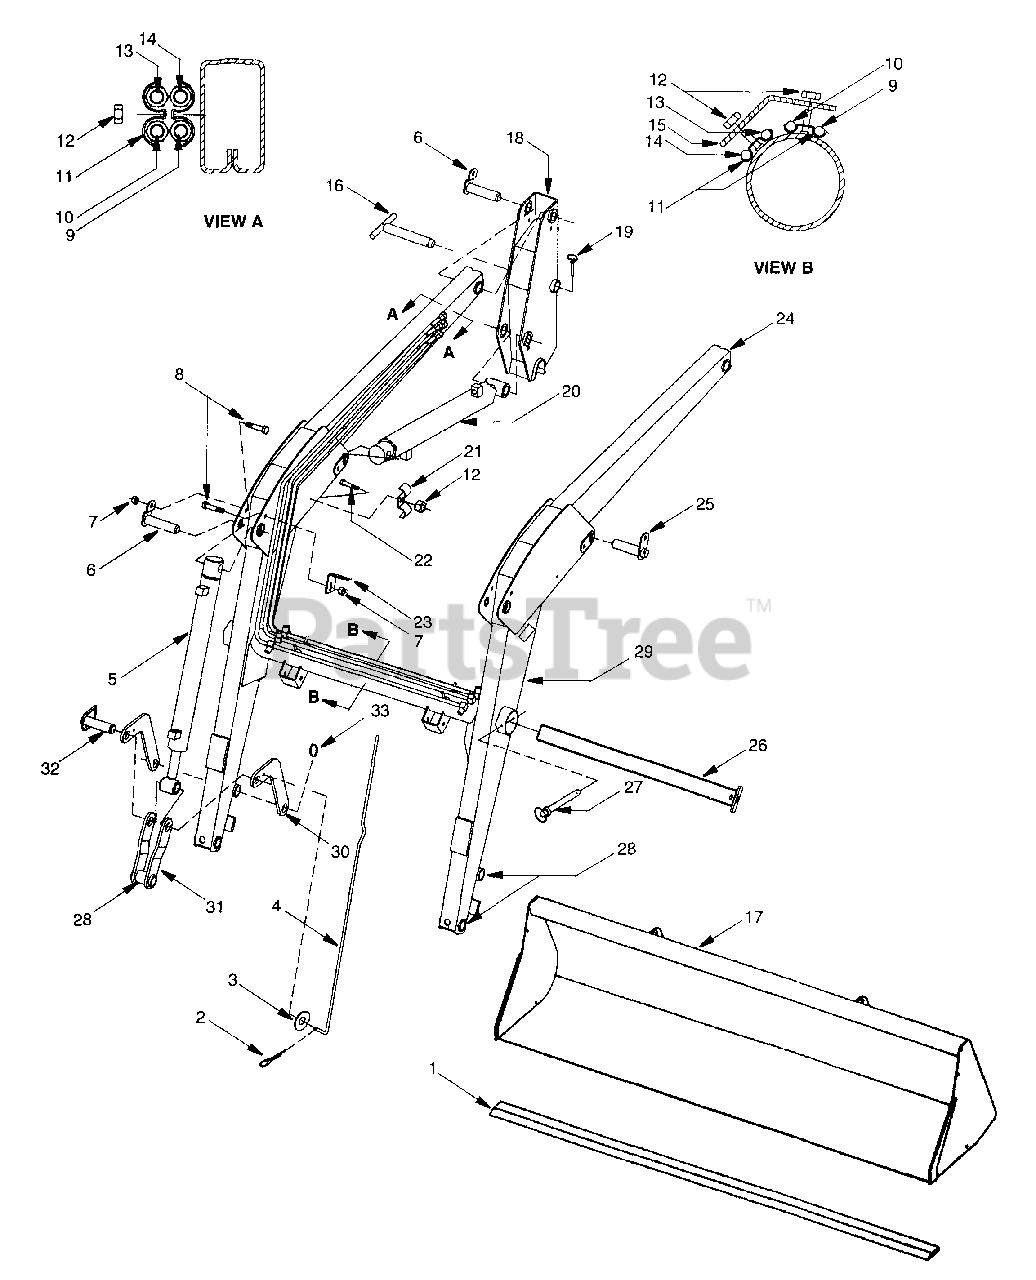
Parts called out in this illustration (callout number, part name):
1	66" Cutting Edge
2	Cotter Pin, 1/8 x 1
3	Flat Washer, 3/8
4	Level Indicator Rod
5	Hydraulic Cylinder-Bucket, 2.0 x 1.0 x 16.75
6	Pin Weldment, 1.25 x 4.58
7	Locknut, 3/8
8	Carriage Bolt, GR5 3/8 x 1
9	Feedline, Boom, Cylinder Rod
10	Feedline, Boom, Cylinder Base
11	Feedline Clamp, 1/2
12	Flanged Lock Nut, 5/16
13	Feedline, Bucket, Cylinder Rod
14	Feedline, Bucket, Cylinder Base
15	Feedline Cover
16	Pull Pin, 1.25 Dia. w/Lynch Pin
17	Bucket, 66"
18	Right Upright
19	Klik Pin, .25
20	Hydraulic Cylinder, Boom, 2.0 x 1.25 x 19.75
21	Feedline Clamp, 5/8
22	Hex Cap Screw, GR5 5/16 x 3/4
23	Bucket Level Indicator Bracket
24	Grease Fitting, 1/4-28 x 90
25	Pin Weldment
26	Parking Stand Weldment
27	Cotterless Hitch Pin
28	Grease Fitting, 1/4-28
29	Boom Weldment
30	Guide Link
31	Bucket Link Weldment
32	Pin (Bucket Link)
33	Snap Ring
